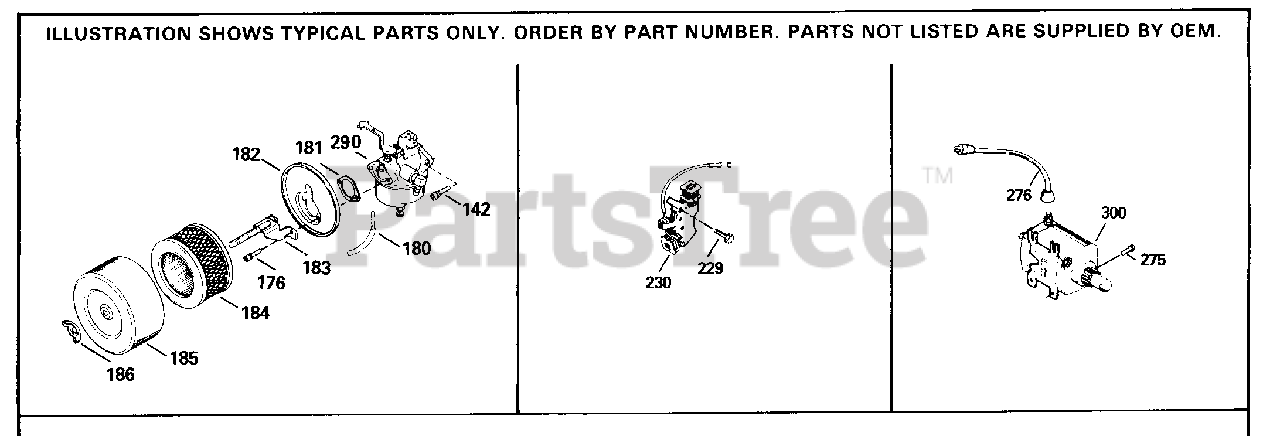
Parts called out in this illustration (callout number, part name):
142	Screw, 1/4-20 x 27/32"
176	Screw, 10-32 x 1/2"
275	Screw, T-30, 1/4-20 x 1/2"
290	Carburetor (Incl. 146) (Refer to Divi sion 5, Section A, page 198 for break down)
